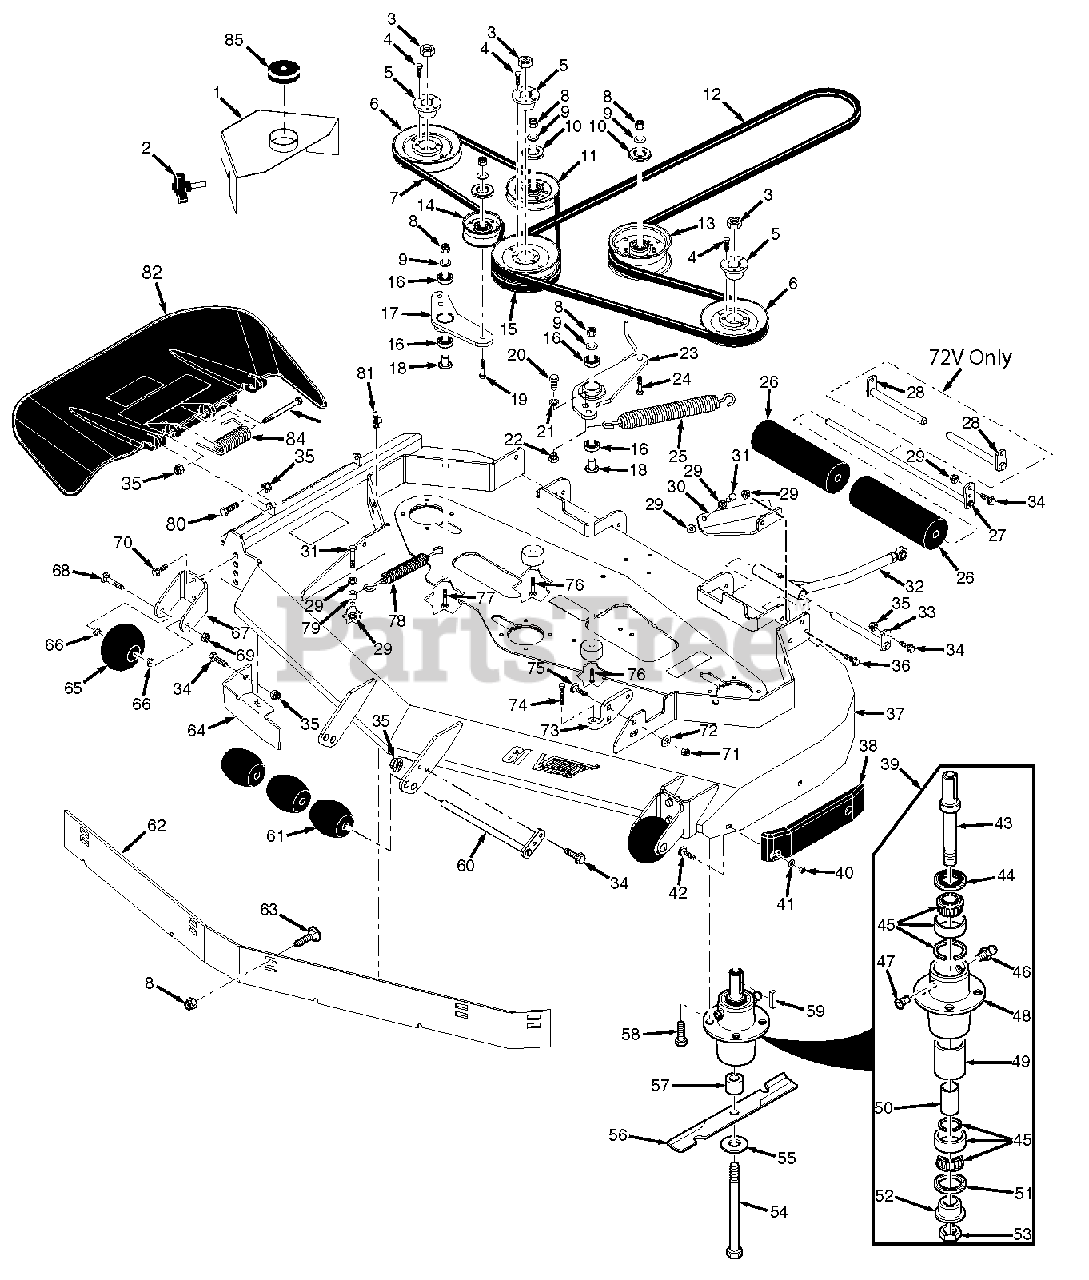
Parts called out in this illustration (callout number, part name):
1	Belt Cover, 61V
1	Belt Cover, 72V
2	Knob w/Stud
3	Nut, 5/8-11 UNC
4	Bolt, Hex Head 1/4-20 x 1"
5	Tapered Hub, 1.125" Bore
6	Pulley, 6.32" Dia.
6	Pulley, 7.50" Dia.
8	Nut, Elastic Stop 3/8-16
9	Flatwasher, 3/8-.391 x .938 x .105
10	Dust Shield
11	Pulley, Idler
12	Belt, Deck Drive
13	Pulley, 5" Idler
14	Pulley, 3-1/2" Idler
15	Pulley, 6.32" Dia. Double Groove
15	Pulley, 7.50" Dia. Double Groove
16	Bearing
17	Idler Arm Assy.
18	Pivot, Idler
19	Bolt, Hex Head 3/8-16 x 2-1/2"
20	Bolt, Hex Head 7/16-14 x 1"
21	Lockwasher, 7/16" Spring
22	Boss, Spring Anchor
23	Idler Arm Assy. (incl. #16)
24	Bolt, Hex Head 3/8-16 x 3"
25	Spring, LH Cutter Deck
26	Guide Roller
27	Shaft Weldment
28	Shaft Weldment
29	Nut, Serrated Flange 3/8-16
30	Spring Mount, SCZ
31	Bolt, Hex Head 3/8-16 x 1-1/2"
32	Pusharm Assy., LH
32	Pusharm Assy., RH
33	Rod Weldment, Pusharm
34	Bolt, Hex Head 5/16-18 x 1"
35	Nut, Elastic Stop 5/16-18
36	Bolt, Hex Head 3/8-16 x 1"
37	Cutter Deck w/Decals
38	Wear Pad
39	Spindle Assembly
40	Nut, Center Lock 5/16-18
41	Flatwasher, 5/16-.344 x .688 x .065
42	Bolt, Carriage 5/16-18 x 3/4"
43	Shaft, Spindle
44	Seal, Top
45	Bearing Assembly
46	Grease Fitting
47	Relief Fitting, Spindle
48	Spindle Housing
49	Spacer, Outside
50	Spacer, Inside
51	Seal, Bottom
52	Spindle Bushing
53	Nut, Special 1-1/16 - 18
54	Bolt, Hex Head 5/8-11 x 9-1/2"
55	Flatwasher, 5/8-.688 x 1.75 x .134 HD
56	Cutter Blade, 21"
56	Cutter Blade, 24-1/2"
57	Spacer, Spindle Bottom
58	Bolt, Hex Head 5/16-18 x 1-3/4"
59	Key, 1/4 x 1/4 x 2"
60	Shaft Weldment
61	Wheel, Anti-Scalp
62	Baffle, Flange - 61V
62	Baffle, Flange - 72V
63	Bolt, Carriage 3/8-16 x 1"
64	Baffle, Turbo - 61V
64	Baffle, Turbo - 72V
65	Wheel, Anti-Scalp
66	Bushing, .376 ID Oilite
67	Bracket, Anti-Scalp Wheel
68	Bolt, Carriage 3/8-16 x 4"
69	Nut, Center Lock 3/8-16
70	Bolt, Hex Head 3/8-16 x 1" Serrated Flange
71	Nut, Elastic Stop 7/16-14
72	Flatwasher, 1/2-.531 x 1.062 x .095
73	Lever Assembly, Deck Level
74	Bolt, Deck Adjust
75	Bolt, Carriage 7/16-14 x 1-1/4"
76	Bolt, Hex Head 3/8-16 x 3"
77	Bolt, Hex Head 3/8-16 x 2-1/4"
78	Deck Spring
79	Spacer
80	Bolt, Hex Head 5/16-18 x 1-3/4"
81	U-Nut, 3/8-16
82	Discharge Chute Assy. 61V
82	Discharge Chute Assy. 72V
83	Bolt, Hex Head 5/16-18 x 4-1/2"
84	Spring, Discharge Chute
85	Cap, Spindle
